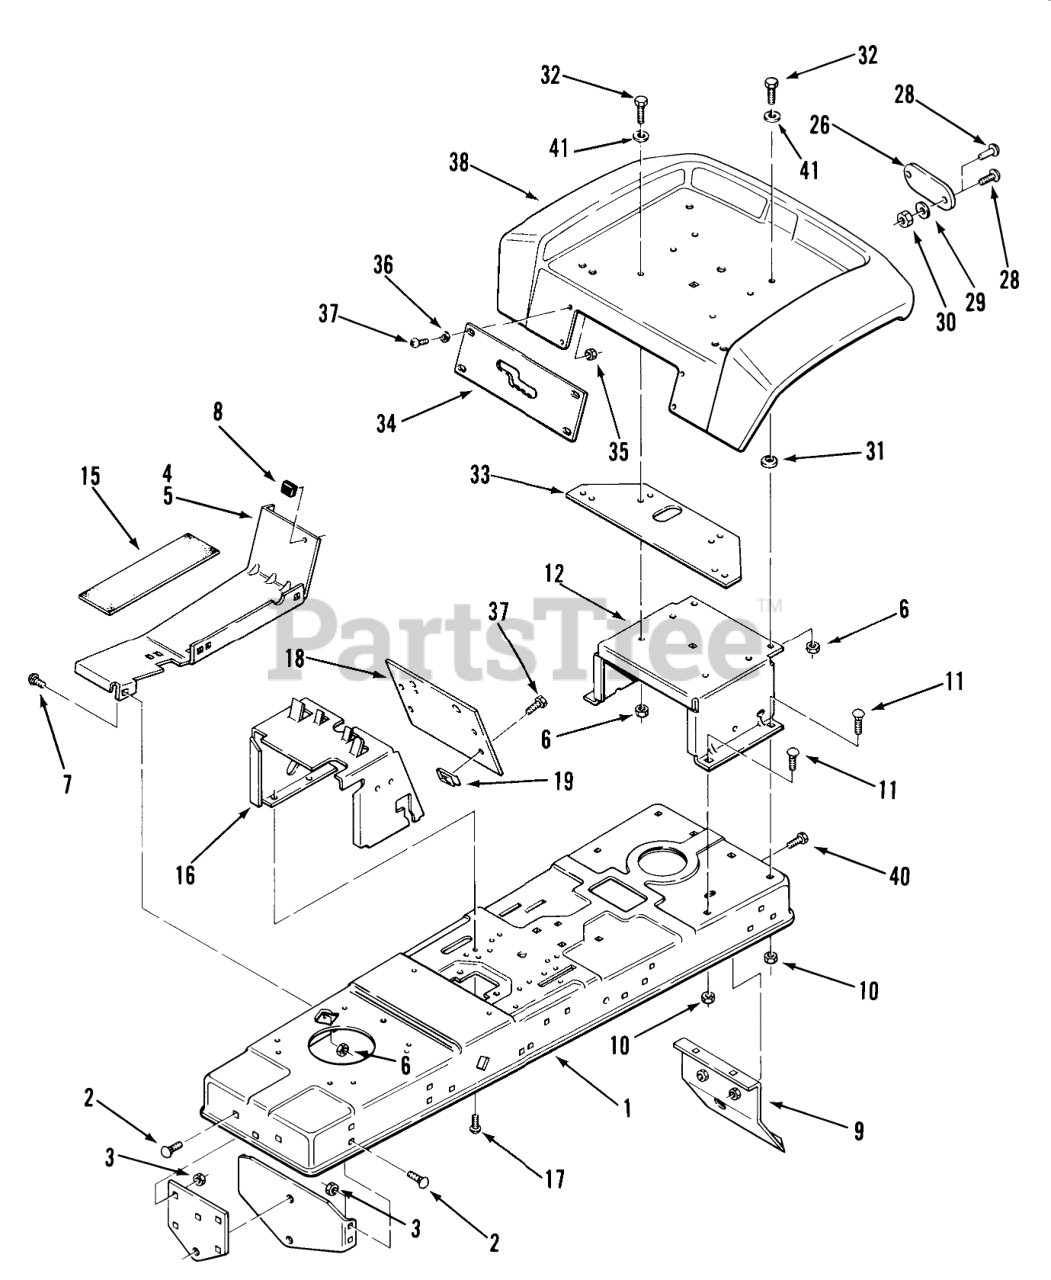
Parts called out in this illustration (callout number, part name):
1	Frame
2	CARRIAGE BOLT -4
3	Nut
4	Footrest RH
5	Footrest LH
6	Nut
7	CARRIAGE BOLT -4
8	BUMPER
9	Hitch-Drawar
10	Nut
11	CARRIAGE BOLT -4
11	Bolt
12	SUPPORT-SEAT R
15	PAD-FOOTREST
16	Hoodstand
17	SCREW
18	Hoodstand Plate
26	Reflector
28	Poprivet
28	Screw
29	Lockwasher
30	Nut
31	WASHER
32	Bolt
32	H H C S
33	PLATE-SEAT R
34	PLATE-SHIFT R
34	PLATE SHIFT R
35	Nut
37	Screw
38	Fender
40	Bolt
41	WASHER 5/16 SAE
